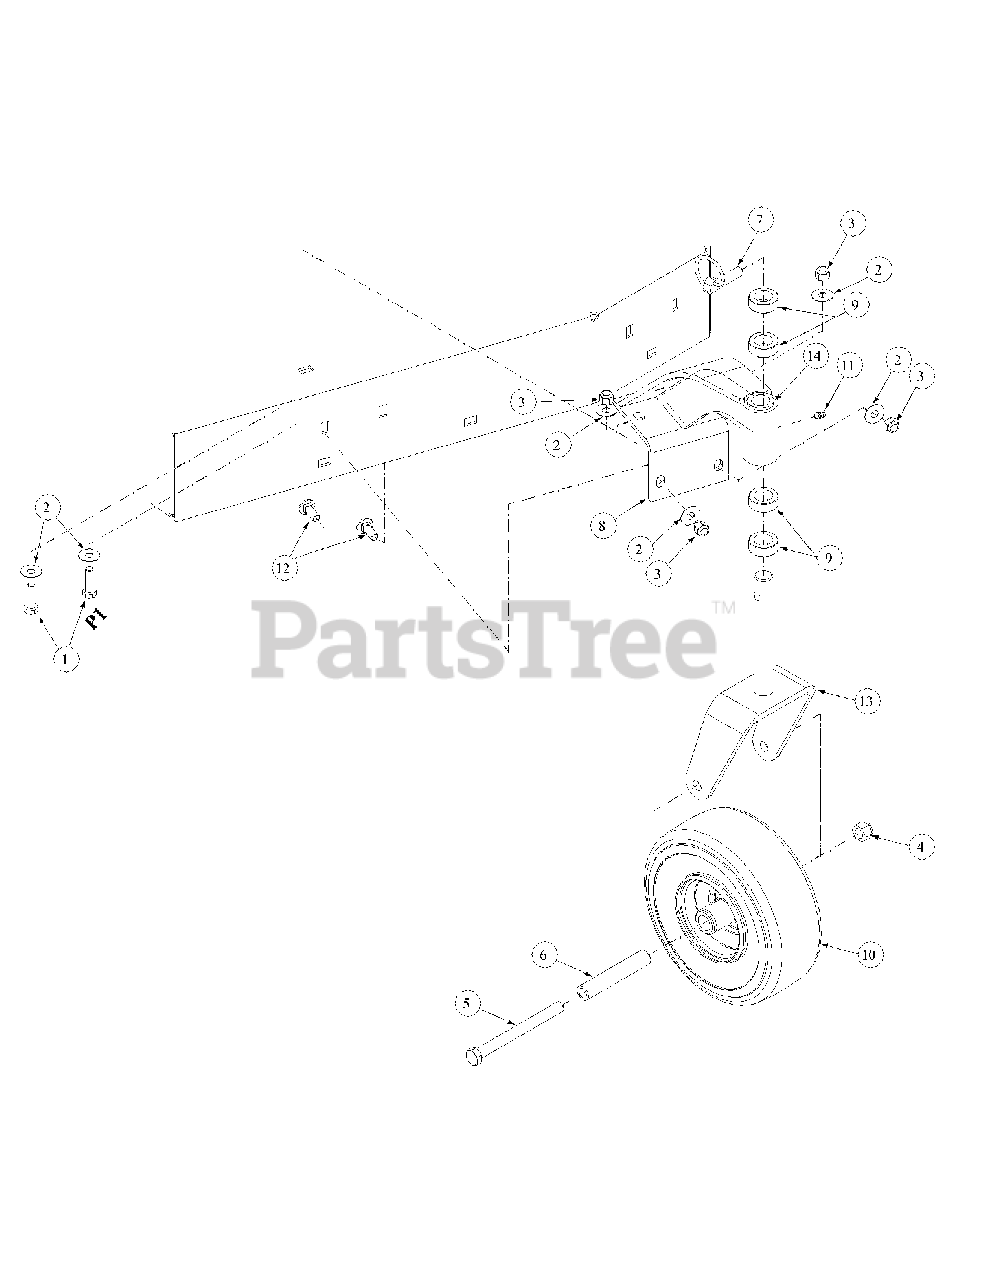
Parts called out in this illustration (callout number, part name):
1	HHCS, Standard 3/8-16 x 1-1/4
2	Flat Washer, 3/8
3	Lock Nut, Nylon Insert 3/8-16
4	Lock Nut, Nylon Insert, 1/2-13
5	HHCS, 1/2-20, 5.5 Lg
6	Spacer Wheel
7	Klik Pin, 1-3/4
8	Caster Bracket Weldment
9	Caster Spacer
10	Wheel Assembly 9.0 x 3.50
11	Grease Fitting, 1/4-28 x 3/16
12	Carriage Bolt, 3/8-16 x 1" Lg
13	Caster Yoke Weldment Assembly
14	Caster Bushing
